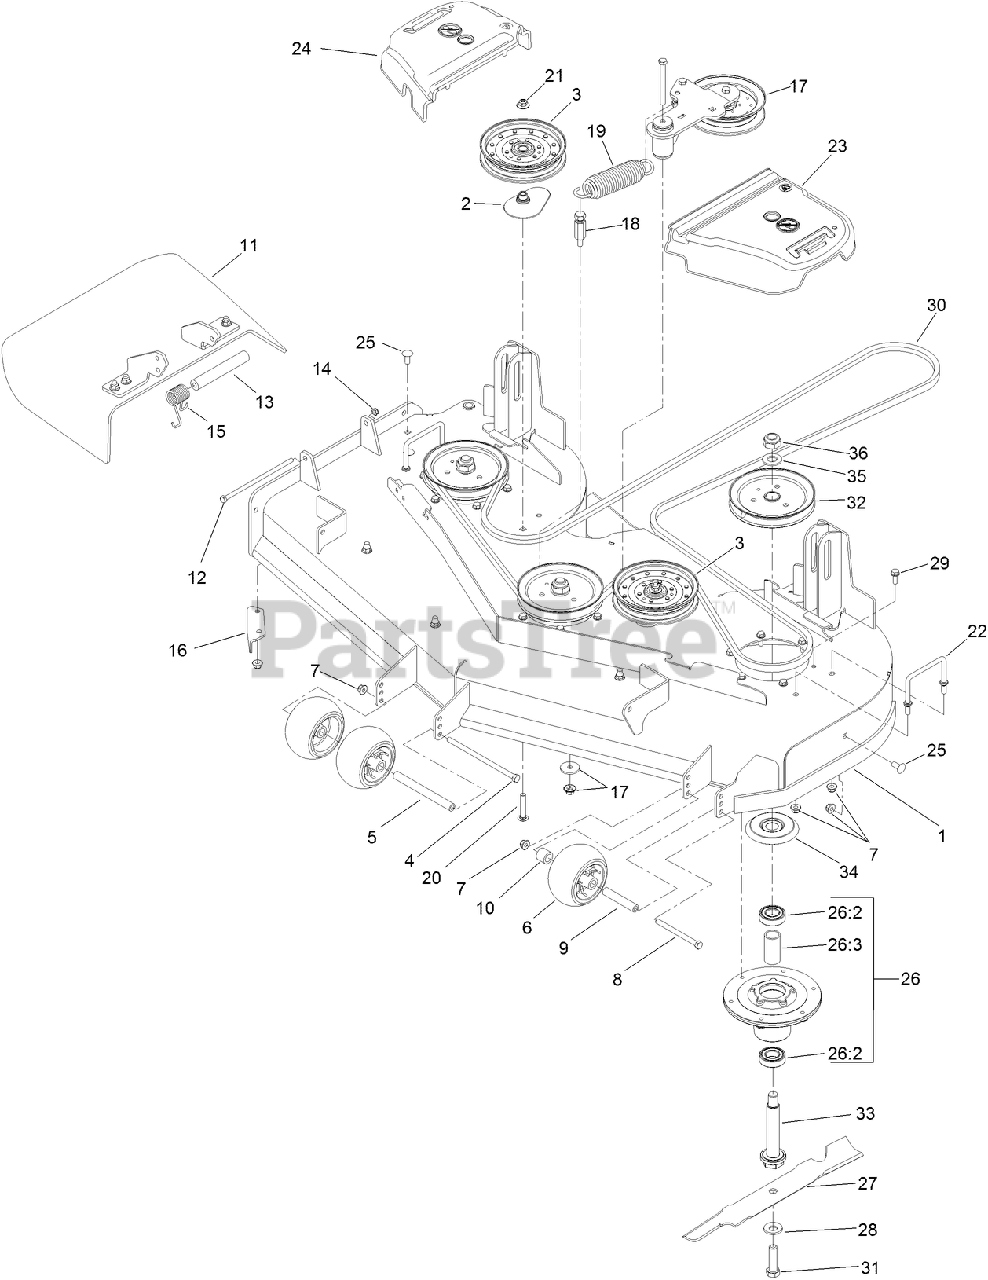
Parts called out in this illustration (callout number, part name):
1	DECK DECAL ASM
2	SPACER-PULLEY
3	PULLEY-IDLER, FLAT
4	SCREW-HH
5	SPACER-WHEEL
6	ROLLER-SCALP, ANTI
7	NUT-HF, NI
8	SCREW-HH
9	TUBE-SPANNER
10	TUBE-SPACER
11	DEFLECTOR ASM
12	SCREW-HH
13	SPACER
14	NUT-LOCK, NI
15	SPRING-TORSION
16	BAFFLE-DISCHARGE
17	IDLER ARM ASM
18	ANCHOR-SPRING, TALL
19	SPRING-EXTENSION
20	BOLT-CARR, SHORT NECK
21	NUT-FLANGE, NI
22	WIREFORM-COVER
23	COVER-BELT, LH
24	COVER-BELT, RH
25	SCREW-CARR
26	SPINDLE ASM
26:2	BEARING-BALL
26:3	SPACER-BEARING
27	BLADE-HI FLOW, 18 IN
28	WASHER-BELLEVILLE
29	SCREW-TAPTITE
30	BELT-V
31	SCREW-BLADE
32	PULLEY
33	SPINDLE-SHAFT
34	SHIELD-BEARING
35	WASHER
36	NUT-LOCK, NI
